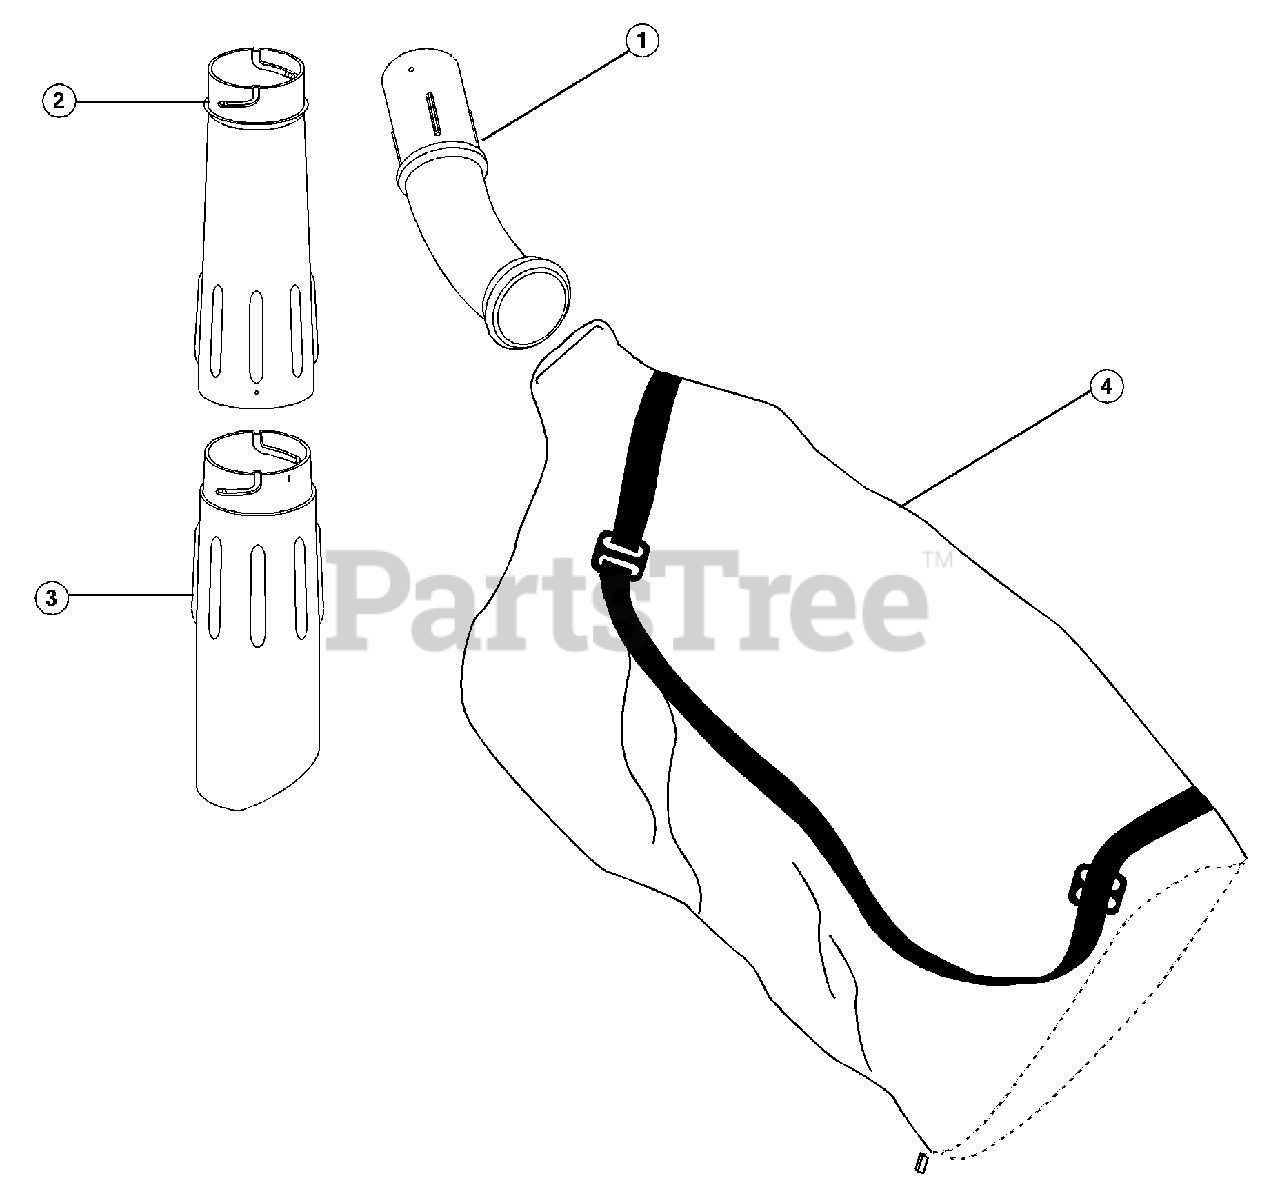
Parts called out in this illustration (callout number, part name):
2	Upper Vacuum Tube & Adapter
3	Lower Vacuum Tube
4	Bag
